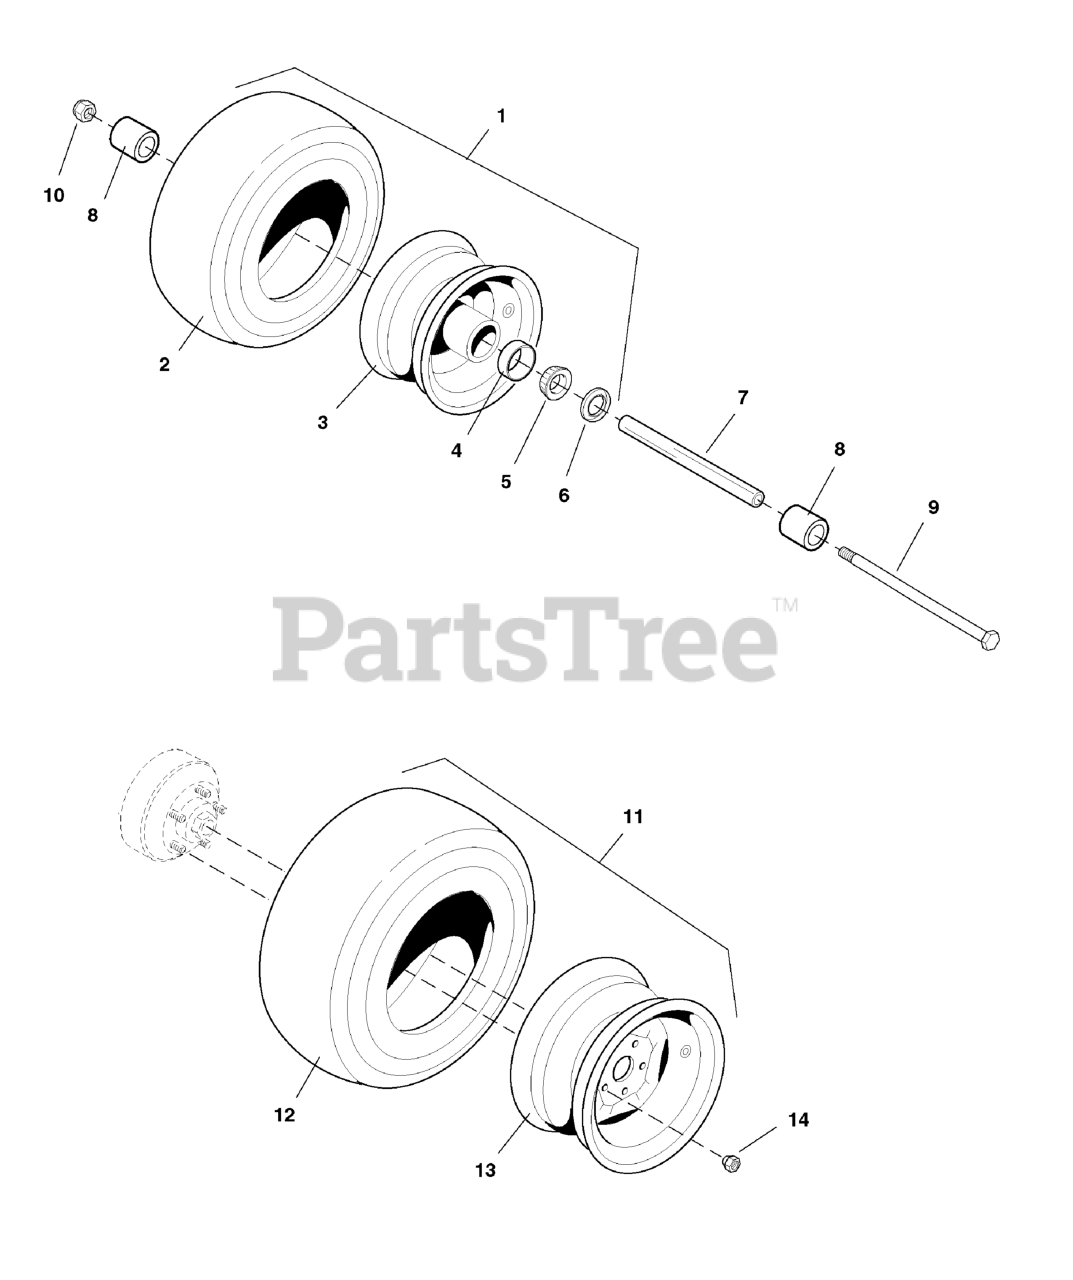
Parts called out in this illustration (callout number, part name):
1	WHEEL & TIRE ASSEMBLY, 18 x 7.5 x 8, Silver, Complete
1	WHEEL & TIRE ASSEMBLY, 18 x 7.5 x 8, White, Complete
2	TIRE, Rear, 18 x 7.5 x 8
3	WHEEL ASSEMBLY, 8 x 3.75, Silver, Complete
3	WHEEL ASSEMBLY, 8 x 3.75, White, Complete
4	BEARING CUP
5	BEARING, Tapered Roller
6	GREASE SEAL
7	STEERING TIRE AXLE
8	SPACER, 1.01 X 1.25 X 2.06
9	BOLT, 5/8-11 x 9-1/2
10	NUT, 5/8-11 Hex Side Lock
11	WHEEL & TIRE ASSEMBLY, 23 x 10.5-12, Silver, Complete
11	WHEEL & TIRE ASSEMBLY, 23 x 10.5-12, White, Complete
12	TIRE, 23 x 10.5-12
13	WHEEL ASSEMBLY, Silver
13	WHEEL ASSEMBLY, White
14	LUG NUT, 1/2-20
